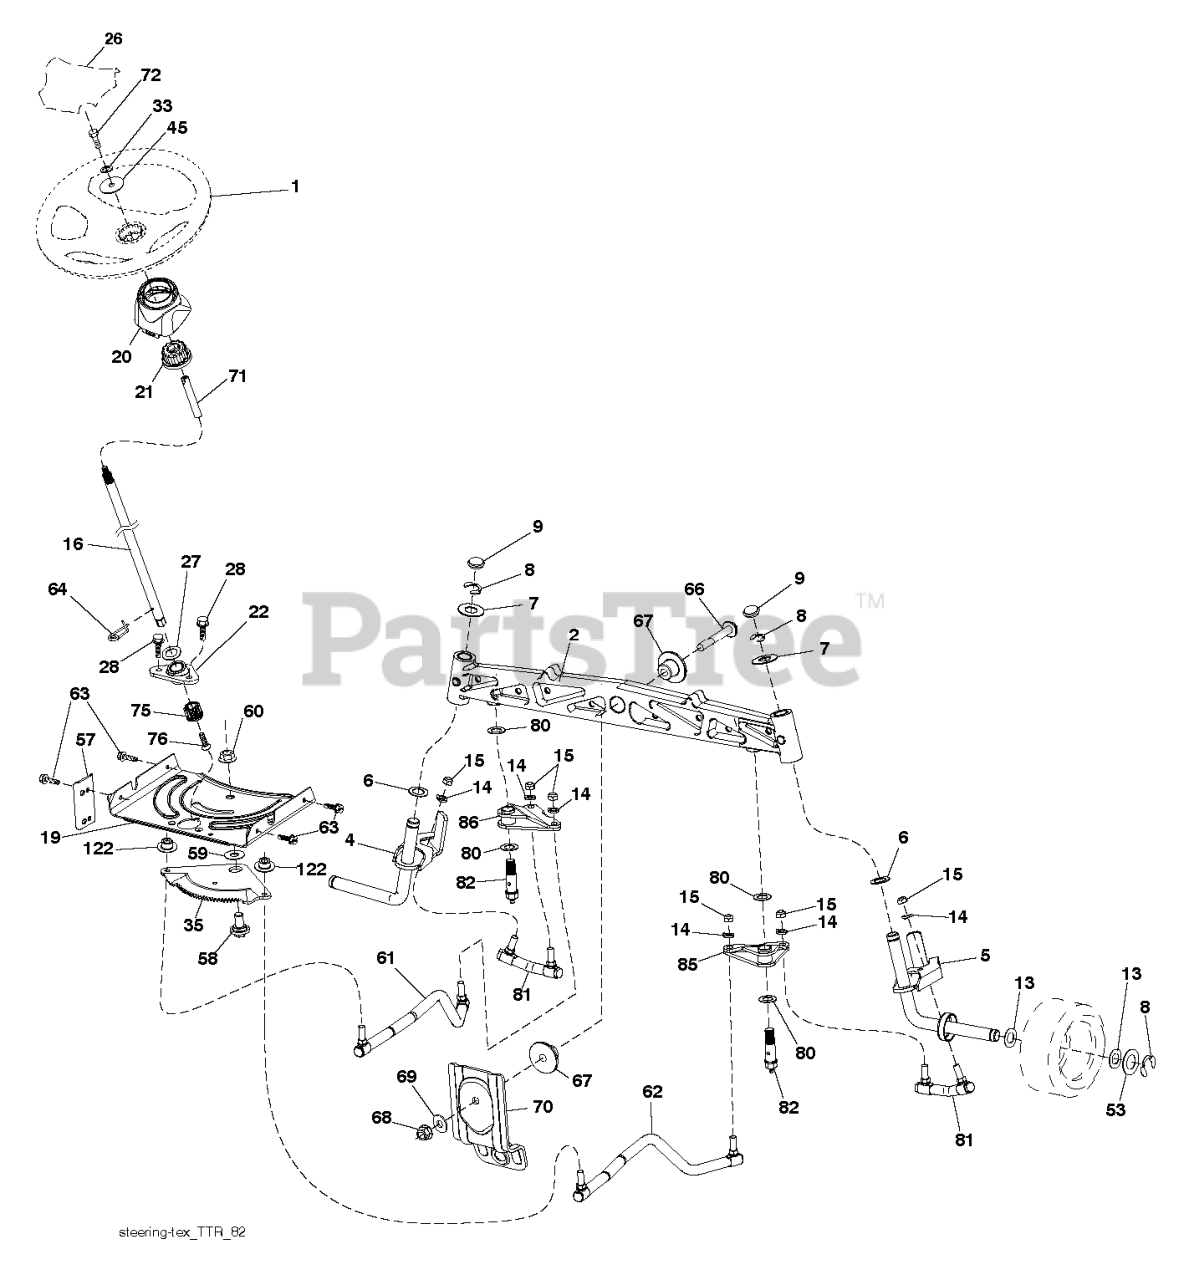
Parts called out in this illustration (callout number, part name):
1	WHEEL.STEER.HUSQ.SR.498.OVMLD
2	RP SUBASM.AXLE.CAST.NZTR.
4	SPINDLE WELDMENT.SPINDLE.LH.15
5	SPINDLE WELDMENT.SPINDLE.RH.15
6	THRUST WASHER
9	CAP.SPINDLE.BLACK
14	WASHER, LOCK 3/8
15	NUT CROWNLOCK 3/8-24
16	3 HIGH.SHAFT-ZINC.PLATED
19	PLATE.STEER.DDL.NLT/NG
20	STEERING.BOOT.HUSQ.LT
21	STEERING.WHEEL.ADAPTER
22	BEARING.SUBASM.SHAFT.STEER.LOW
26	INSERT.CAP.WHL.STRG.HUSQ.PREM
28	SCREW, 3/8-16X3/4
33	WASHER.LOCK.HVY.HLCL.SPR.5/16
35	GEAR GEAR.SECTOR.TEX.NZTR
45	WASHER.11/32
53	WASHER.HARDENED
57	BRACKET.UPSTOP.TEX
58	BOLT.SHOULDER.SECTOR.P
59	WASHER.THURST.SECTOR.S
60	NUT FLANGE LOCK 5/8-11
61	LINK ASSY DRAGLOINK, ADJUSTABL
62	DRAGLINK,ADJUSTABLE,RH
63	SCREW
64	RETAINER.CLIP.SPRING.S
66	BOLT HEX FGHD 7/16-14 X 3 SERR
67	BUSHING.PM.FRONT AXLE
68	NUT.LOCK.FLANGE.7/16
69	WASHER.1.5X.505X.118
70	BRACKET.FRT.DECK.SUSP.RR.MT431
71	SHAFT.EXTEN.STRG.SPLINE
72	BOLT 5/16-18 X 4 W/PATCH
75	PINION.ZINC PLATED
76	SCREW HEAD SOCKET LRVB
80	THRUST WASHER
81	LINK SUBASM.LINK.CROSS.NZTR
82	SUBASM;PIVOT;BOLT;NZTR
85	PIVOT SUBASM.PIVOT.RH.NZTR
86	PIVOT SUBASM.PIVOT.LH.NZTR
122	CAP.GEAR.SECTOR.TEX
